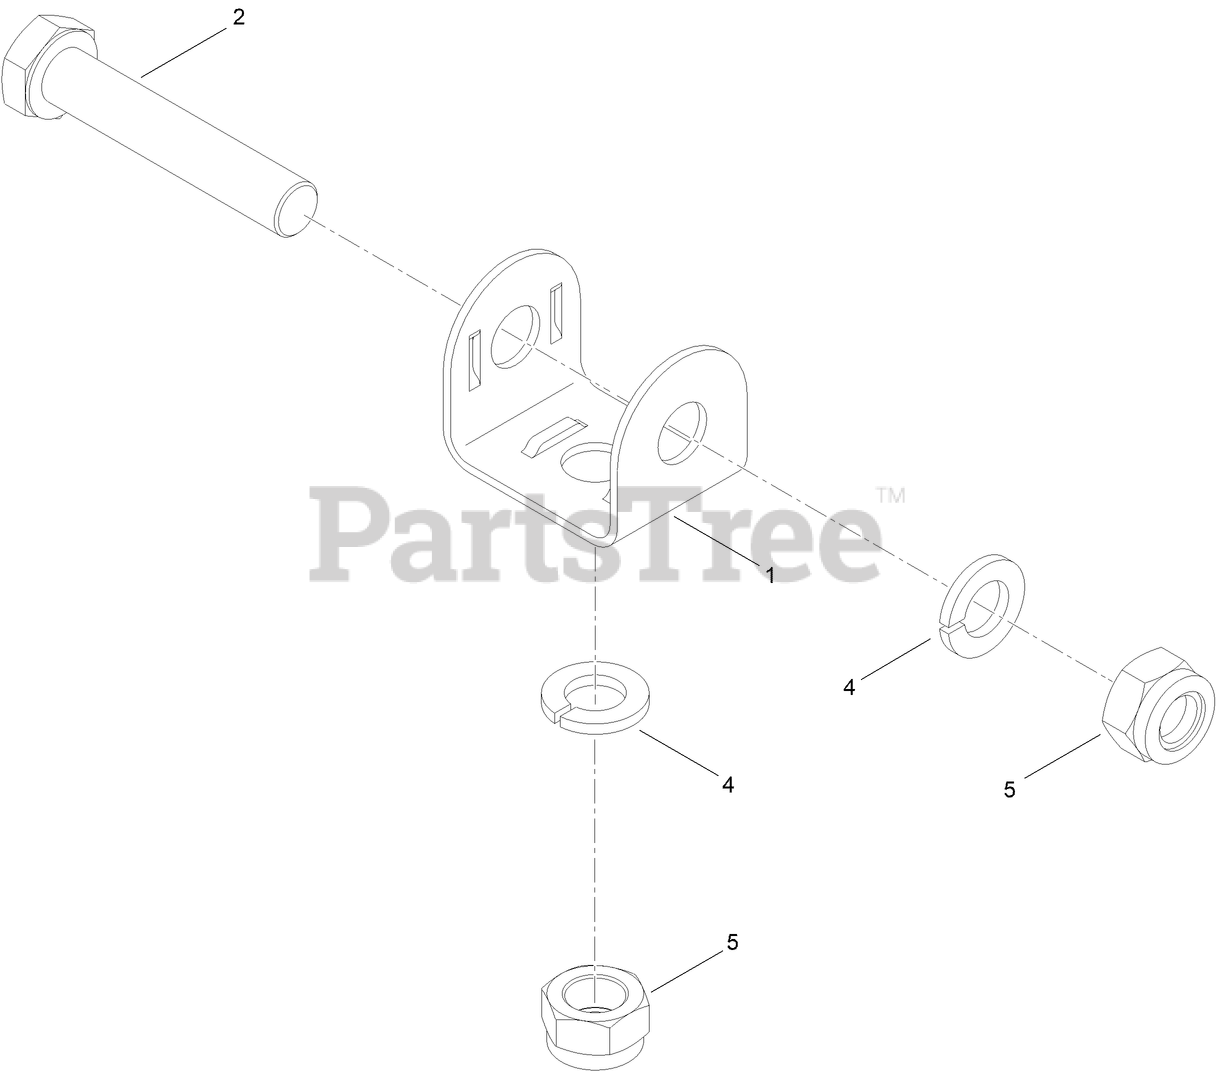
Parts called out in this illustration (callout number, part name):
1	MOUNT-LIGHT
2	SCREW-HH
4	WASHER-LOCK
5	NUT-HEX
